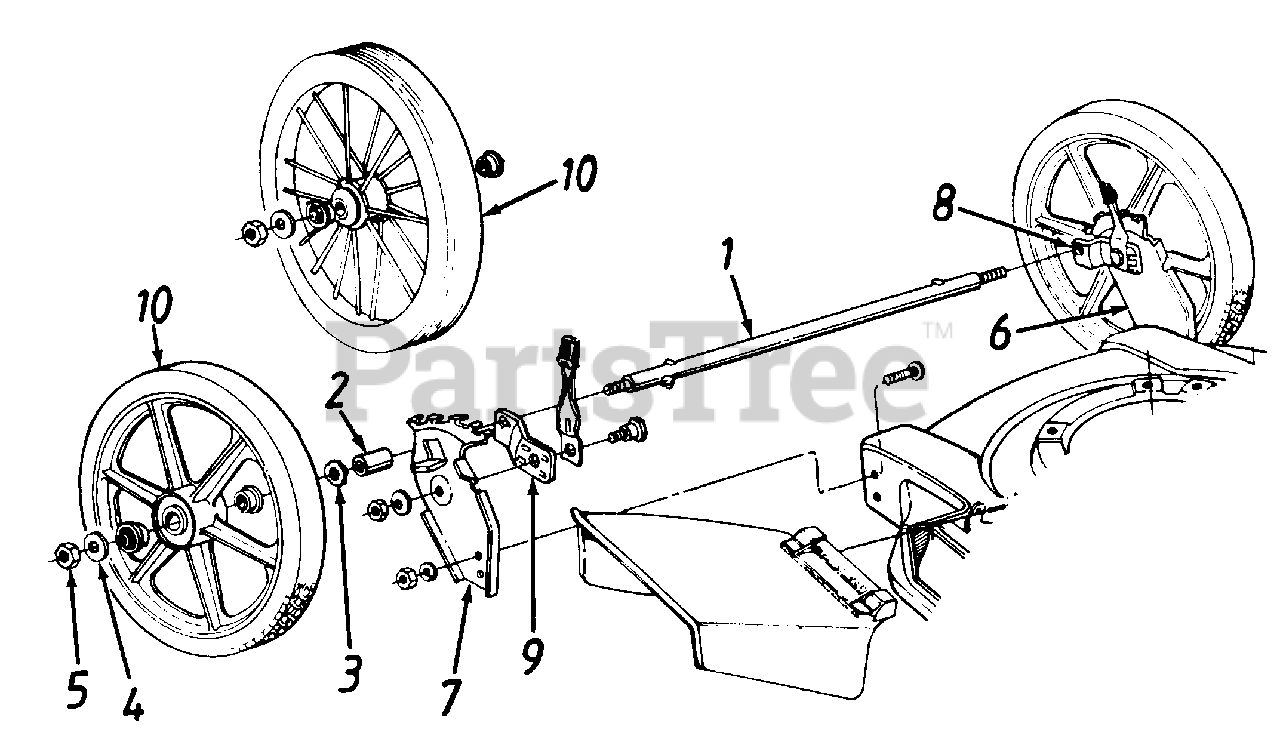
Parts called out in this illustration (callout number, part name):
1	Rear Axle .500 Dia. x 22.83
2	Spacer .550 I.D. x .755 O.D.
3	Wave Washer.510 I.D. x .750 O.D.
4	Flat Washer.406 I.D. x .8100.D.
5	Hex Ins Top-L Jam Nut 3/8 - 16
9	Small Pivot Bar - RH
10	Rear Wheel Ass'y. 16" (Plastic)
